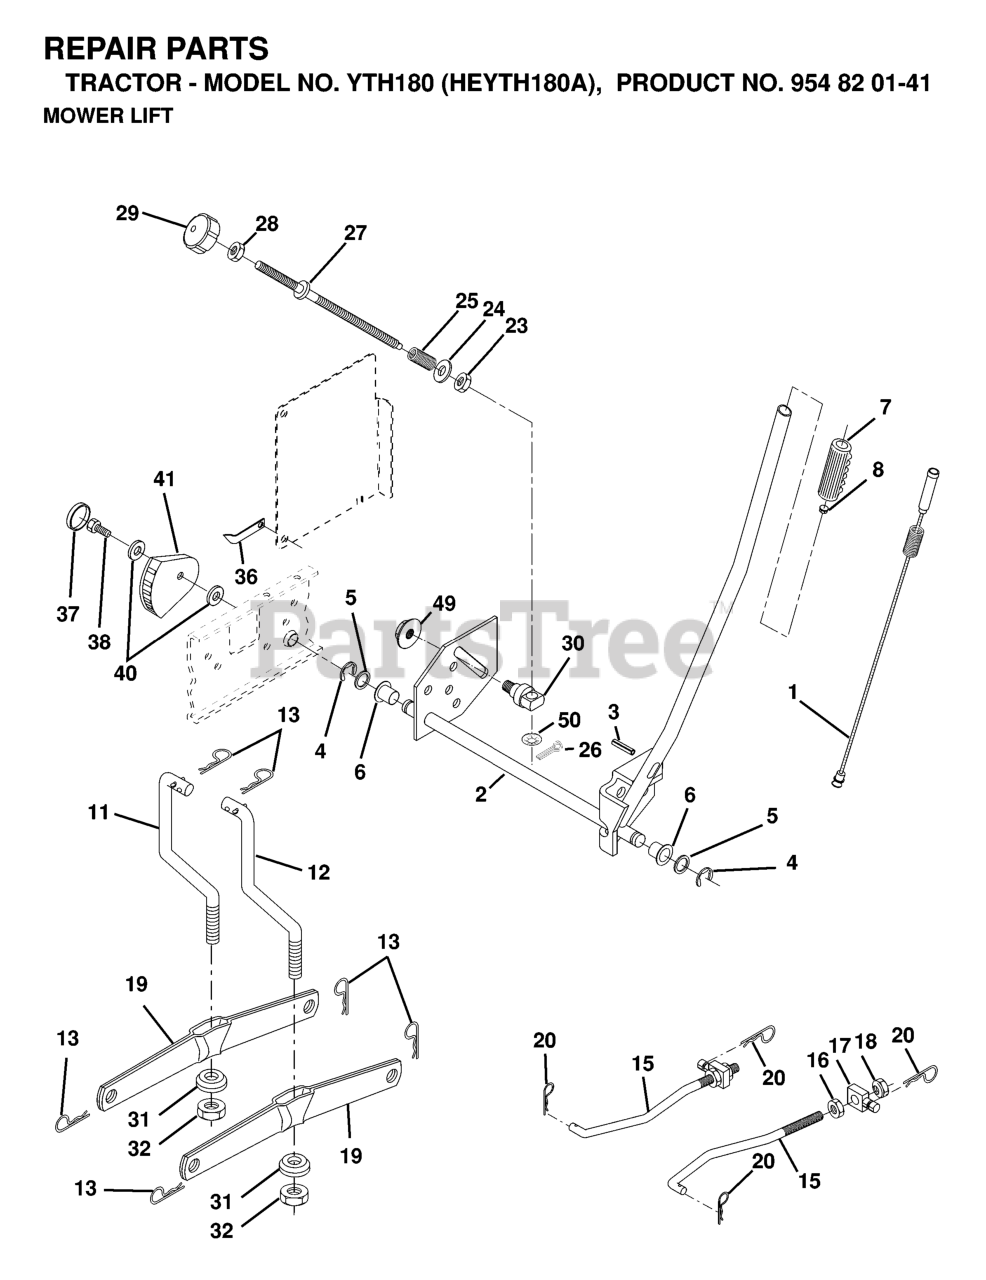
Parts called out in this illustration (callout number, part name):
1	WIRE ASM INNER W/ PLUNGER LT
2	SHAFT ASM R HANDLE
3	PIN GROOVE.
4	RETAINING RING LT
6	BEARING.NYLON
7	GRIP HANDLE
8	PLUNGER BUT KIT
11	LINK LIFT LH
12	LINK LIFT RH
13	RETAINER-SPRNG RB
15	FRONT LINK
16	NUT.HEX.JAM.1/2-13
17	TRUNION
18	NUT LTV
19	ARM.REAR.SUSPENSION
20	SPRING RETAINER
25	SPRING**
26	COTTER PIN
27	ROD ADJ LIFT
28	NUT
29	KNOB INF 3/8-16
31	NUT CROWNLOCK 3/8-24
32	BEARING PIVOT
36	POINTER, HEIGHT INDICATOR(2 2)
38	SCREW.THDROL.5/16-18X3/4.TTY
41	IND. HEIGHT STLT
49	NUT
50	NUT PUSH M
